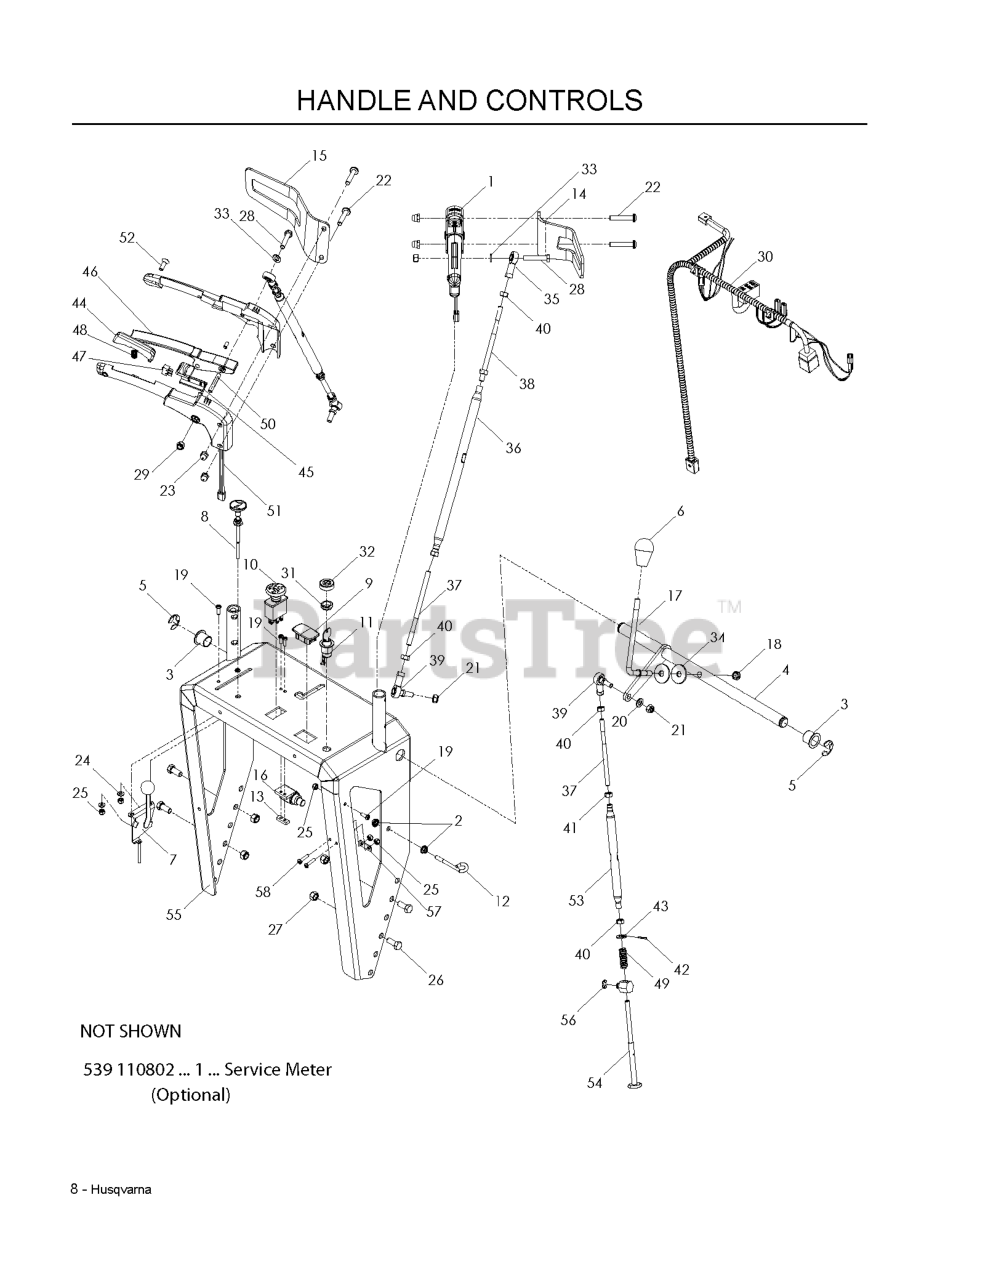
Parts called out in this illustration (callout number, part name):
2	NUT 5/16C WHIZ
3	BEARING - FLANGE, 20MM
4	SPEED CONTROL
5	E-RING, 20MM
6	KNOB - SHIFT
7	THROTTLE CONTROL
8	CONTROL-CHOKE 51"
9	PLUG DASH
10	RP.SWITCH, BLADE
11	KEY SWITCH, COMPLETE
12	GUIDE - ROPE
13	TAPPED PLATE
14	GUARD, HAND - OFFSET RH, PTD
15	GUARD, HAND - OFFSET LH, PTD
16	SWITCH, NC PLUNGER
17	ROD-SHIFT R/B 522676001
18	NUT HEX 3/8-16 NYLON, THIN
19	HCS #10-24 X 1/2
20	FLAT WASHER 5/16 SAE
21	NUT M8-1.25 TOP NYL GR10 ZD
22	SCR. PAN HD - 5/16-18 X 1.75 L
23	NUT ACORN 5/16-18
24	WASHER #10
25	NUT 10-24 NYLOC
26	HCS 3/8-16 X 7/8 GR 5 ZD
27	NUT 3/8-16 NYLOC
28	HCS 5/16C X 1 3/4
29	NUT 5/16 NYLOC
30	HARNESS, UPPER HANDLE
31	DNO IGNITION NUT
32	CAP IGNITION NUT
33	WASHER.LOCK.HVY.HLCL.SPR.5/16
34	CONE WASHER
35	ROD END 8 MM, RH
36	TUBE - ADJUSTING
39	ROD END 8 MM, W/STUD
40	NUT 8MM X 1.25 HEX ZD
42	ROLL PIN - 3 MM
44	OPC ACTUATOR
45	LOCK - NEUTRAL
50	PIN - GROOVE 1/4 X 1-1/2
51	HARNESS - SWITCH
52	SCREW - OVAL HEAD 6MM
53	TUBE - ADJUSTING
55	HANDLE W/DECAL
56	E-RING, 10MM
57	MODULE
58	SCREW, #1--24 X 1/2 SLOTTED
